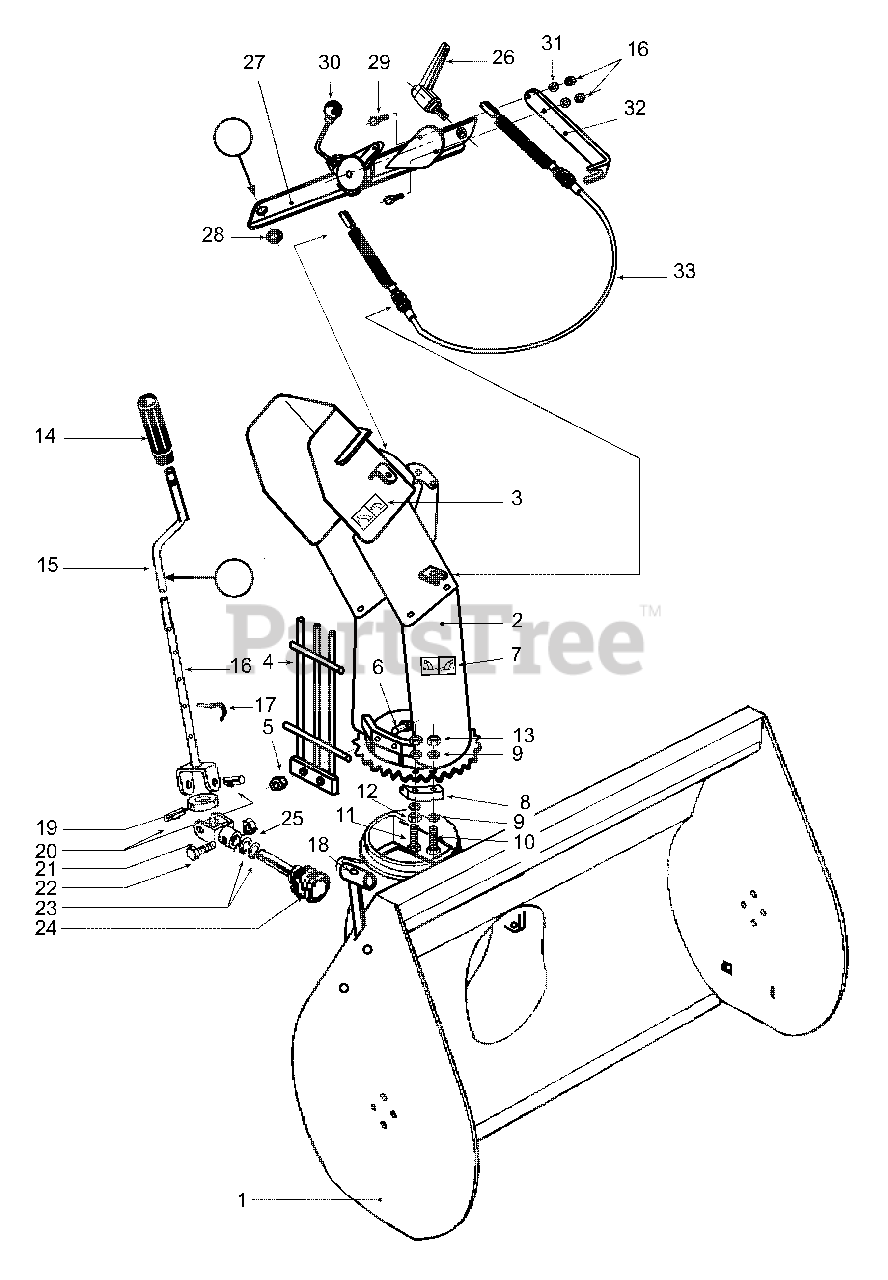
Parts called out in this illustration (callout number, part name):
1	Snow Thrower Main Body, 85 Cm Wide - SX 370
2	Ejection Chimney
3	Label - "Flap Up/Down"
4	Chimney Safety Guard
5	Self Locking Nut M8 - Din 985
6	Hexagonal Head Screw M8 x 30 - Din 933
7	Label - "Chimney Rotation"
8	Aluminum Block
9	Washer 6.4 x 12 x 1.6 Din 125a
10	Hexagon Head Screw M6 x 35 - Din 933
11	Hexagon Head Screw M6 x 40 - Din 933
12	Nut M6 Haut - Uni 5587
13	Self Locking Nut M6 - Din 982
14	Griff
15	Crank - Extractable Part
16	Crank - Adjustable Part
17	Fast Pin Ø 5
18	Grease Nipple M6
19	Cross For Cardan Joint
20	Lok Pin 10 x 18 - Din 1481
21	Clevis For Cardan Joint
22	Hexagonal Head Screw M6 x 35 - Din 931
23	Washer 20.25 x 28 x 0.3
24	Quadruple Screw, Right Hand For Chimney Rotation
25	Self Locking Nut M6 - Din 982
26	Gripping Lever M10 x 20 (Mr80 Pm 10/20)
27	Bracket For Crank And Throttle Lever
28	Plastic Ring
29	Screw M6 x 25 - Din 7991
30	Throttle Lever For Flap Adjustment
31	Washer 6.5 x 12 x 1 Din 125a
32	Bracket For Cable
33	Complete Cable (Length: 1800 mm) For Flap Adjustment
